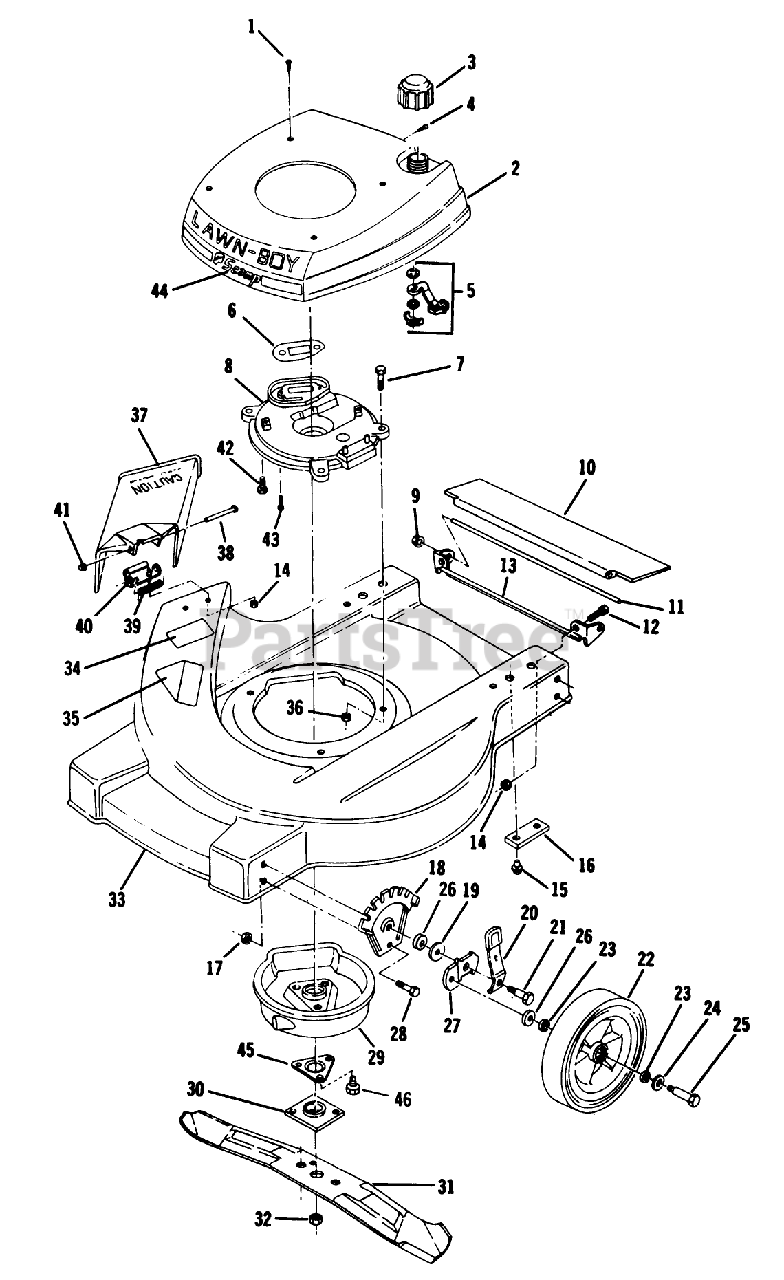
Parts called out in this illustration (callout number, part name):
1	SCREW LAWRENCE
3	FUEL CAP & INSERT
4	SCREW S
7	SCREW-HH
8	PLATE,MUFFLER F
10	TRAILING SHIELD
13	BRACKET (12)
14	LOCKNUT E
15	SCREW
17	LOCKNUT
19	WASHER
20	KNOB & SPRING
21	BOLT
23	WASHER
24	SPACER
25	BOLT WHEEL
26	WASHER WROUGHT
30	PLATE AND COLLAR ASM
32	NUT-BLADE
36	NUT-LOCK F
37	CHUTE DEFLECTOR AY
38	PIN
40	HINGE & SCREW ATA
43	SCREW V
45	SUPPORT F
46	SCREW
